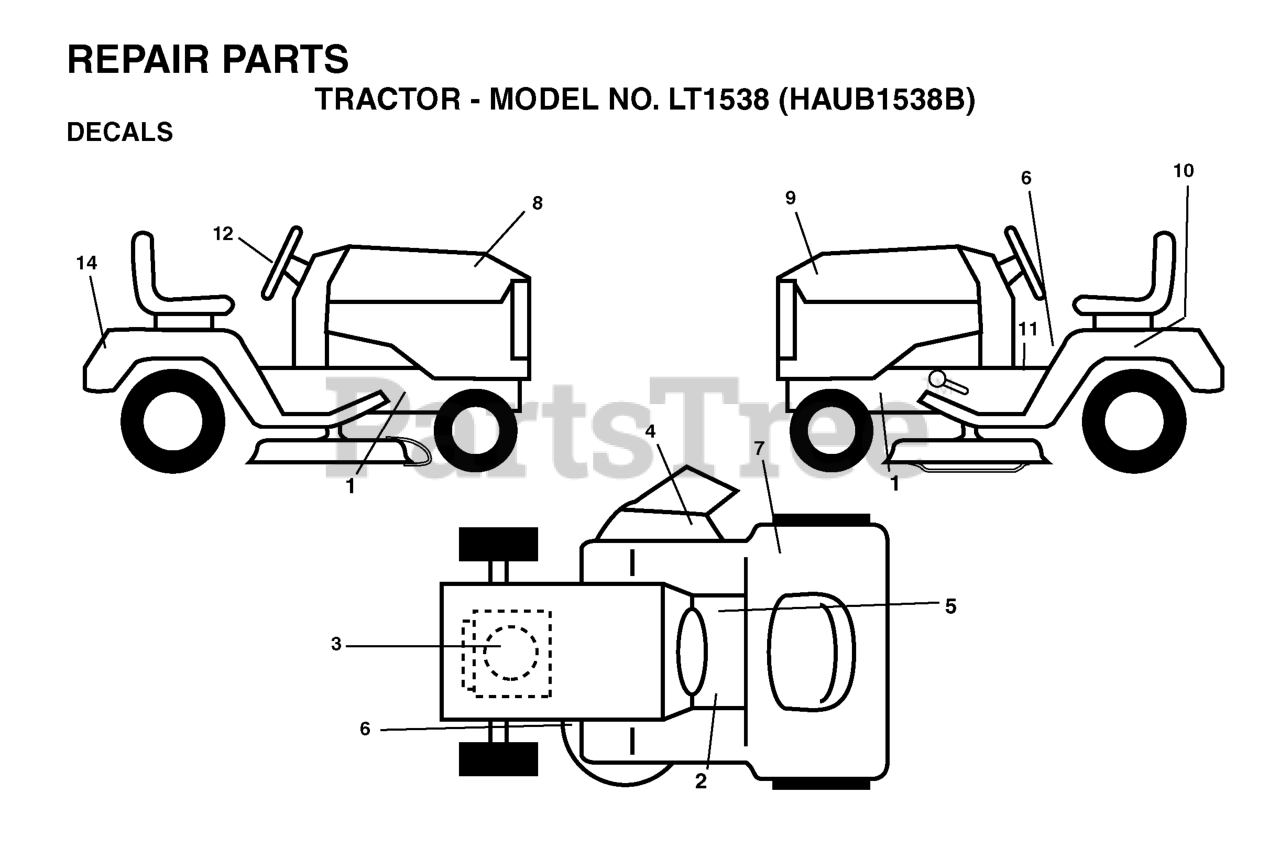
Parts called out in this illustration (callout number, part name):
2	DECAL
4	DECAL.INTERNATIONL.CUTFINGER
5	DECAL PARK BRAKE
6	DECAL V-BELT SCHEMATIC
7	DECAL
10	DECAL BTRY SYMBOLS
11	DECAL READ OWNER'S MAN SYMS
12	DECAL.WHEEL.STEERING.HUSQ.PERM
14	DECAL, FENDER
